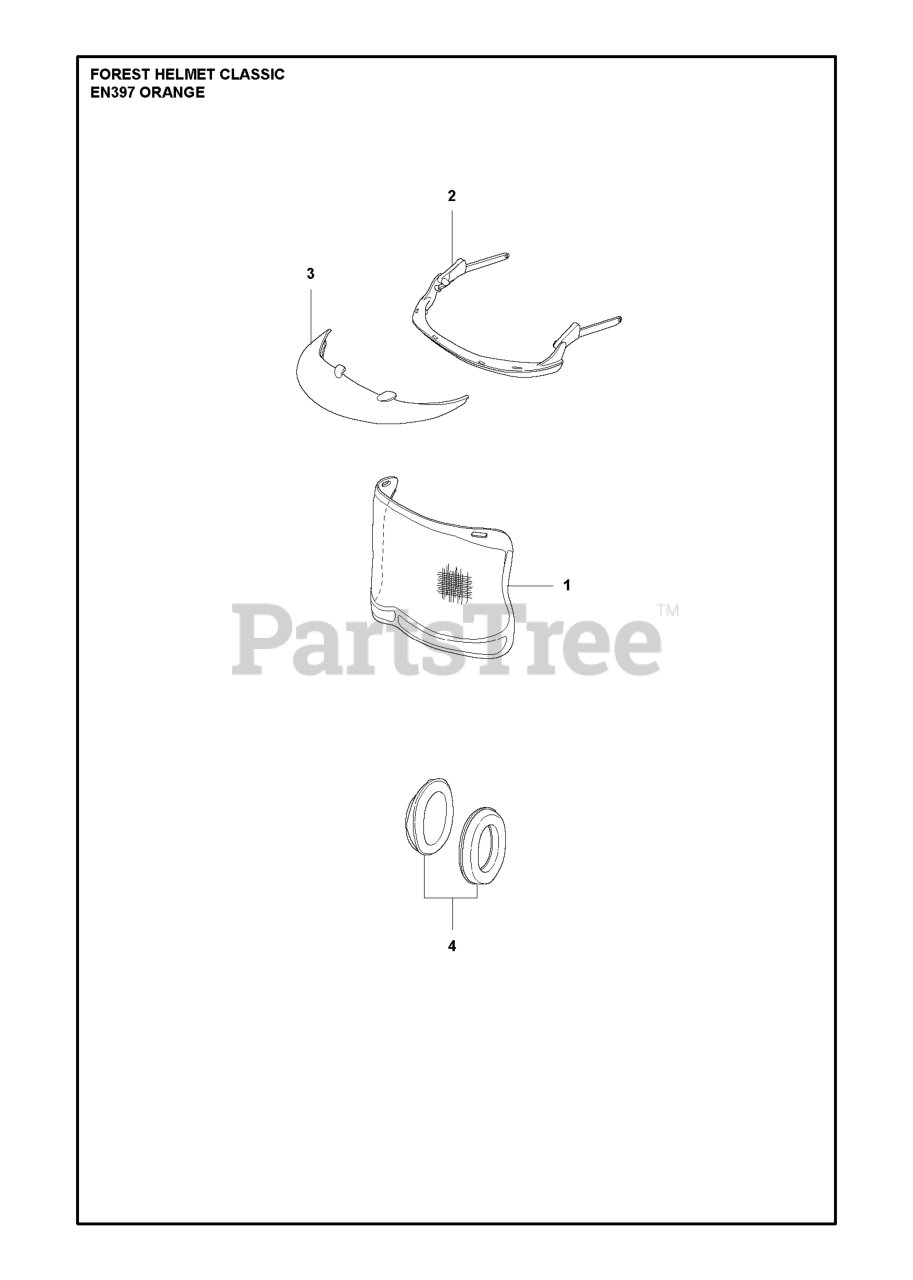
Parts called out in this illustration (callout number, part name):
1	ULTRA VISON VISOR XS
2	VISOR ARM/HOLDER
3	VISOR SHIELD N/A FOR HELMET
4	HYGIENE SET
